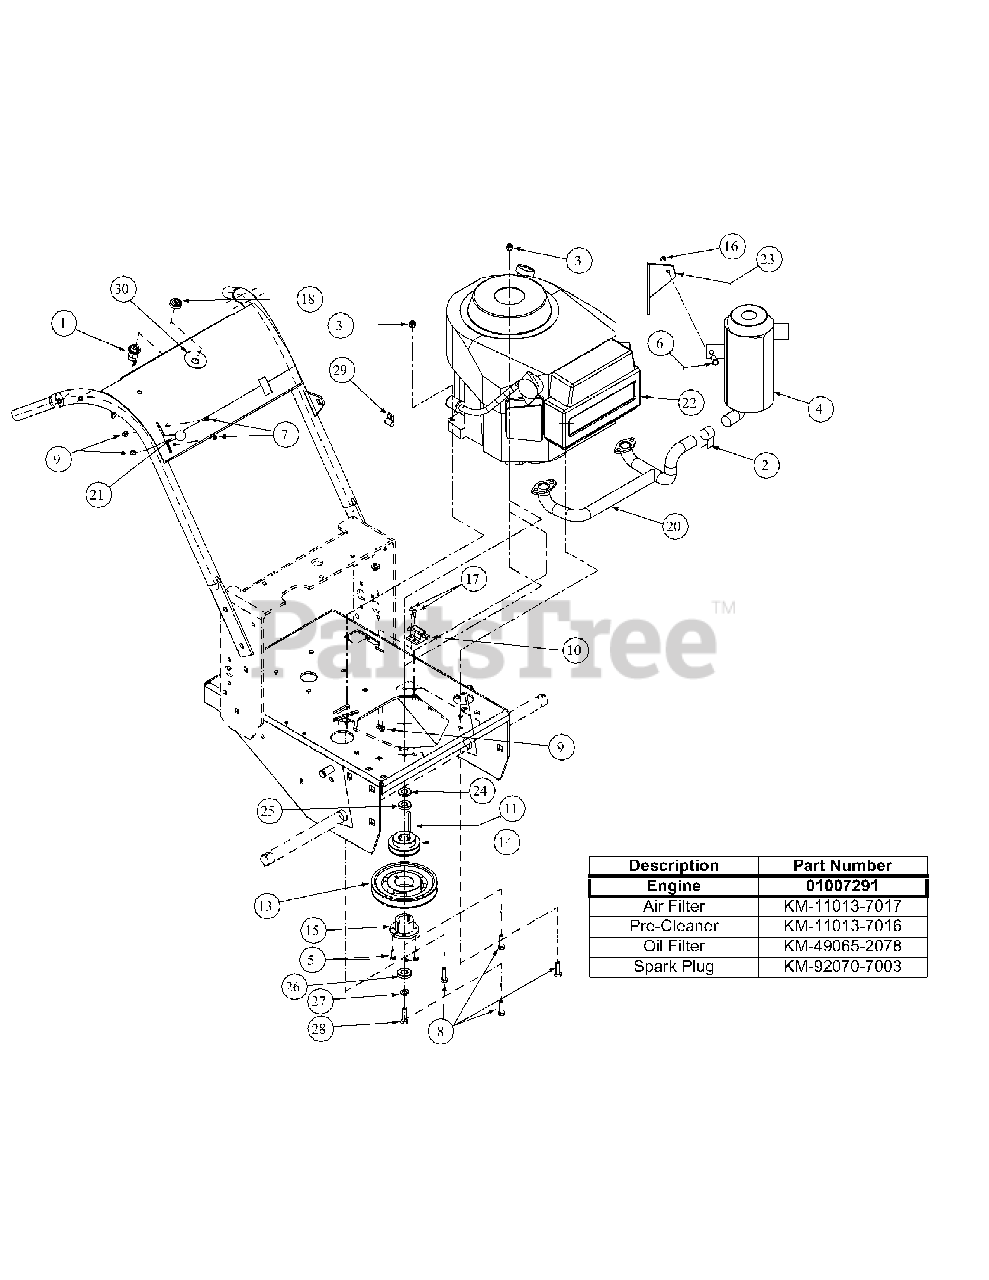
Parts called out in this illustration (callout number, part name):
1	Single Ignition ON/OFF Switch
2	Muffler Clamp Assembly
3	Nut, 5/16-18 Nylock
5	Hex Cap Screw, 1/4-20, .75
6	Hex Cap Screw, 5/16-18 x 3/4
7	Screw, Hex Washer, 10-32 x 1/2
8	Cap Screw, 5/16-18 x 2
9	Lock Nut, Nylon Insert, 10-32
10	Delta Switch
11	Key Stock, 1/4 x 1/4 x 2-3/4
12	Harness Wire
13	Deck Pulley
14	Traction Drive Pulley
15	Bushing Type D
16	Hex Nut, Control Lock, 5/16-18
17	Machine Screw, 10-32 x 5/8
18	Nut, w/Cap, 5/8-32, Ignition
19	Belt Transmission Drive
20	Kawasaki Manifold
21	Throttle Control, w/Detent, 47.25
22	Engine, 15HP Kawasaki
23	Kawasaki Bracket Muffler
24	Engine Pulley Spacer, 12.5 Vanguard
25	Flat Washer
26	Clutch Washer
27	Lock Washer, 7/16
28	Capscrew, 7/16-20 x 1-1/4
29	Support Clamp, 3/8 OD
30	Decal, Pull Start Overlay
